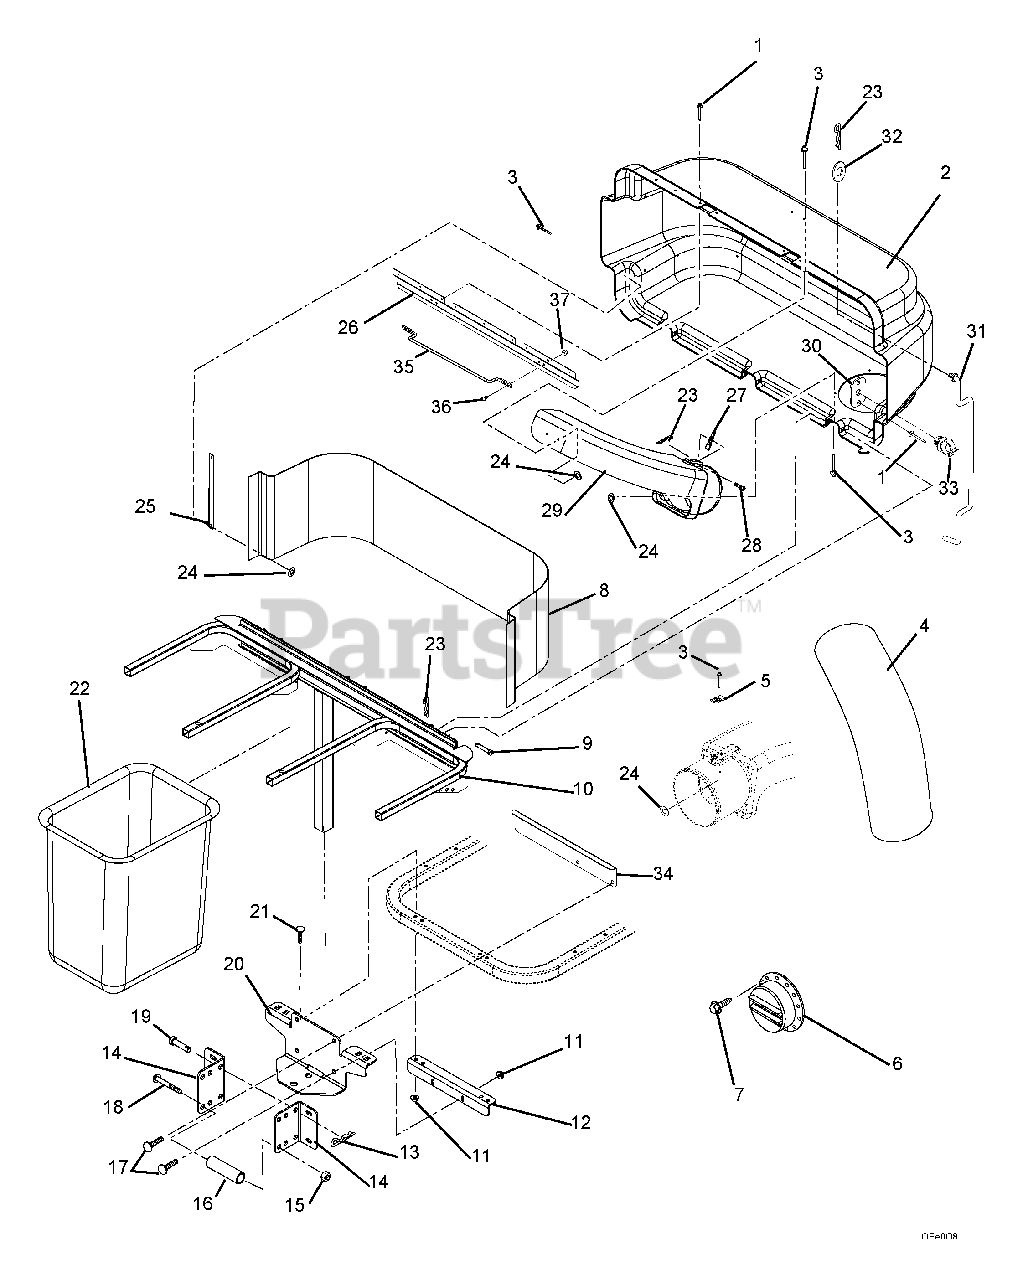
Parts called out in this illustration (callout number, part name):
1	Rivet-Pop .187 x .402
2	Cover, Bagger with Decal
3	Rivet-Pop .187 x .375
4	Hose 7 x 45
5	Thumb Latch
6	Deflector, Exhaust
7	Screw-Tapping 8-32X.38 Slotted Hex Washer Head
8	Screen, Bagger
9	Pin-Clevis .368/.373 x 3.25
10	Weldment, Bagger Frame
11	Nut-Locking-Top-Flange .38-16
12	Bracket,Angle
13	Pin-Hair-External .12 x .31 x 2.37
14	Bracket, Bagger Mount
15	Nut-Locking-Top-Flange .50-13
16	Spacer, Pivot
17	Bolt-Round Head Square Neck .38-16 x 1.25 Grade 5
18	Bolt-Hex .50-13 x 3.00 Grade 5
19	Pin-Clevis .494 x 2.50
20	Trailer Hitch with Decals
21	Bolt-Round Head Square Neck .38-16 x 2.50 - Grade 5
22	Grass Bagger Basket
23	Pin-Hair
24	Washer-Flat-Steel .219 x .50 x .049
25	Strap, Cover
26	Latch, Bagger
27	Indicator, Flow
28	Pin-Clevis .31 x 2.62 Grade 5
29	Boot, Upper
30	Plate, Rod Clip
31	Prop-Rod, Bagger
32	Washer-Flat-Steel .046 x .812 x .065
33	Clip .38
34	Deflector, Exhaust
35	Bagger Handle
36	Bolt, Round Head Square Neck .25-20 x .75 Grade 5
37	Nut, Locking-Top-Flange .25-20
